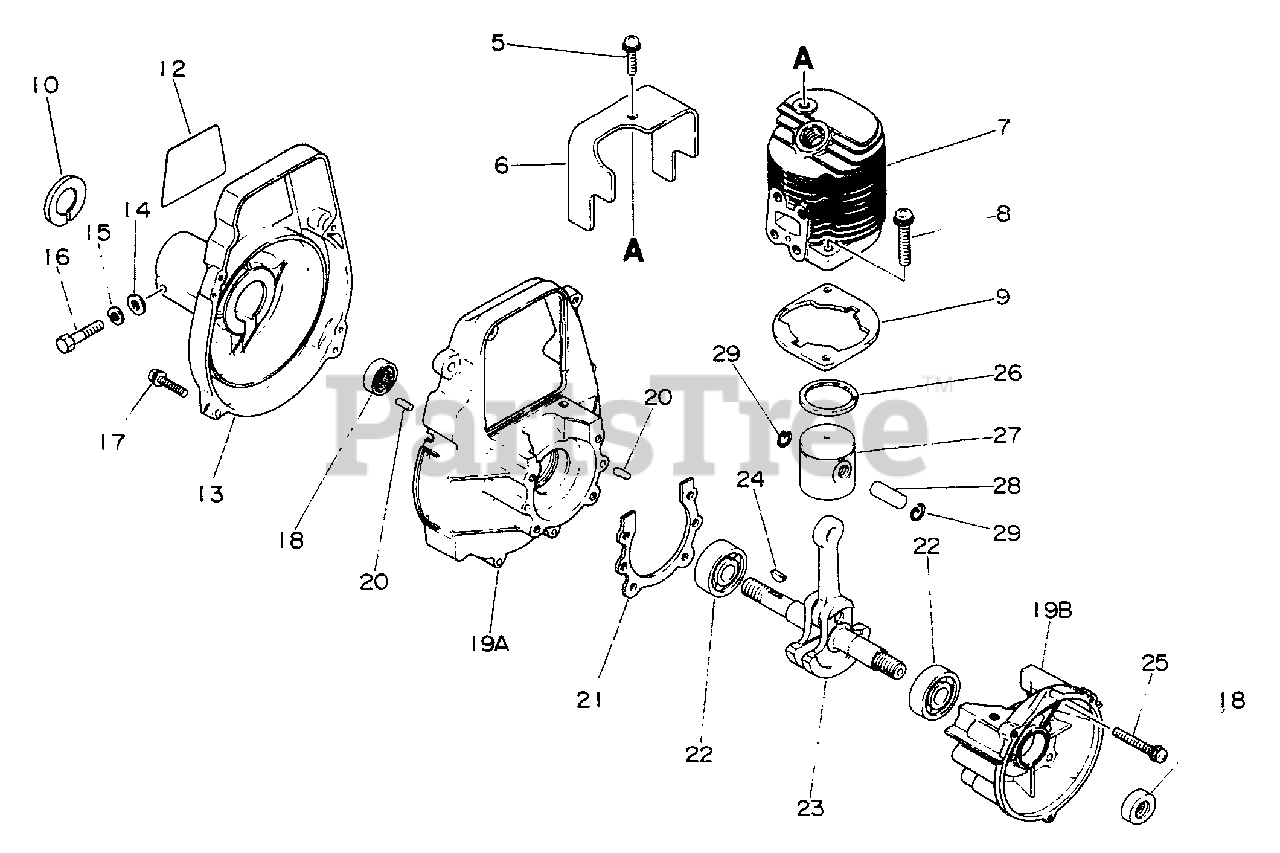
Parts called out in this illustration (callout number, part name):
5	SCREW - 5X10
6	SHIELD, CYLINDER
7	CYLINDER
8	SCREW - 6X20
9	GASKET, CYLINDER
10	SPACER
12	LABEL
13	CASE, FAN
14	WASHER - 5
15	LOCKWASHER - 5
16	BOLT - 5X20
17	SCREW - 4X20
18	SEAL, OIL
19	CRANKCASE KIT
19A	CRANKCASE KIT
19B	CRANKCASE KIT
20	PIN - LOCATING
21	GASKET, CRANKCASE
22	BEARING, BALL - 6200
23	CRANKSHAFT ASSY
25	SCREW - 5X30
26	RING, PISTON
27	PISTON
28	PIN, PISTON
29	RING, RETAINING
